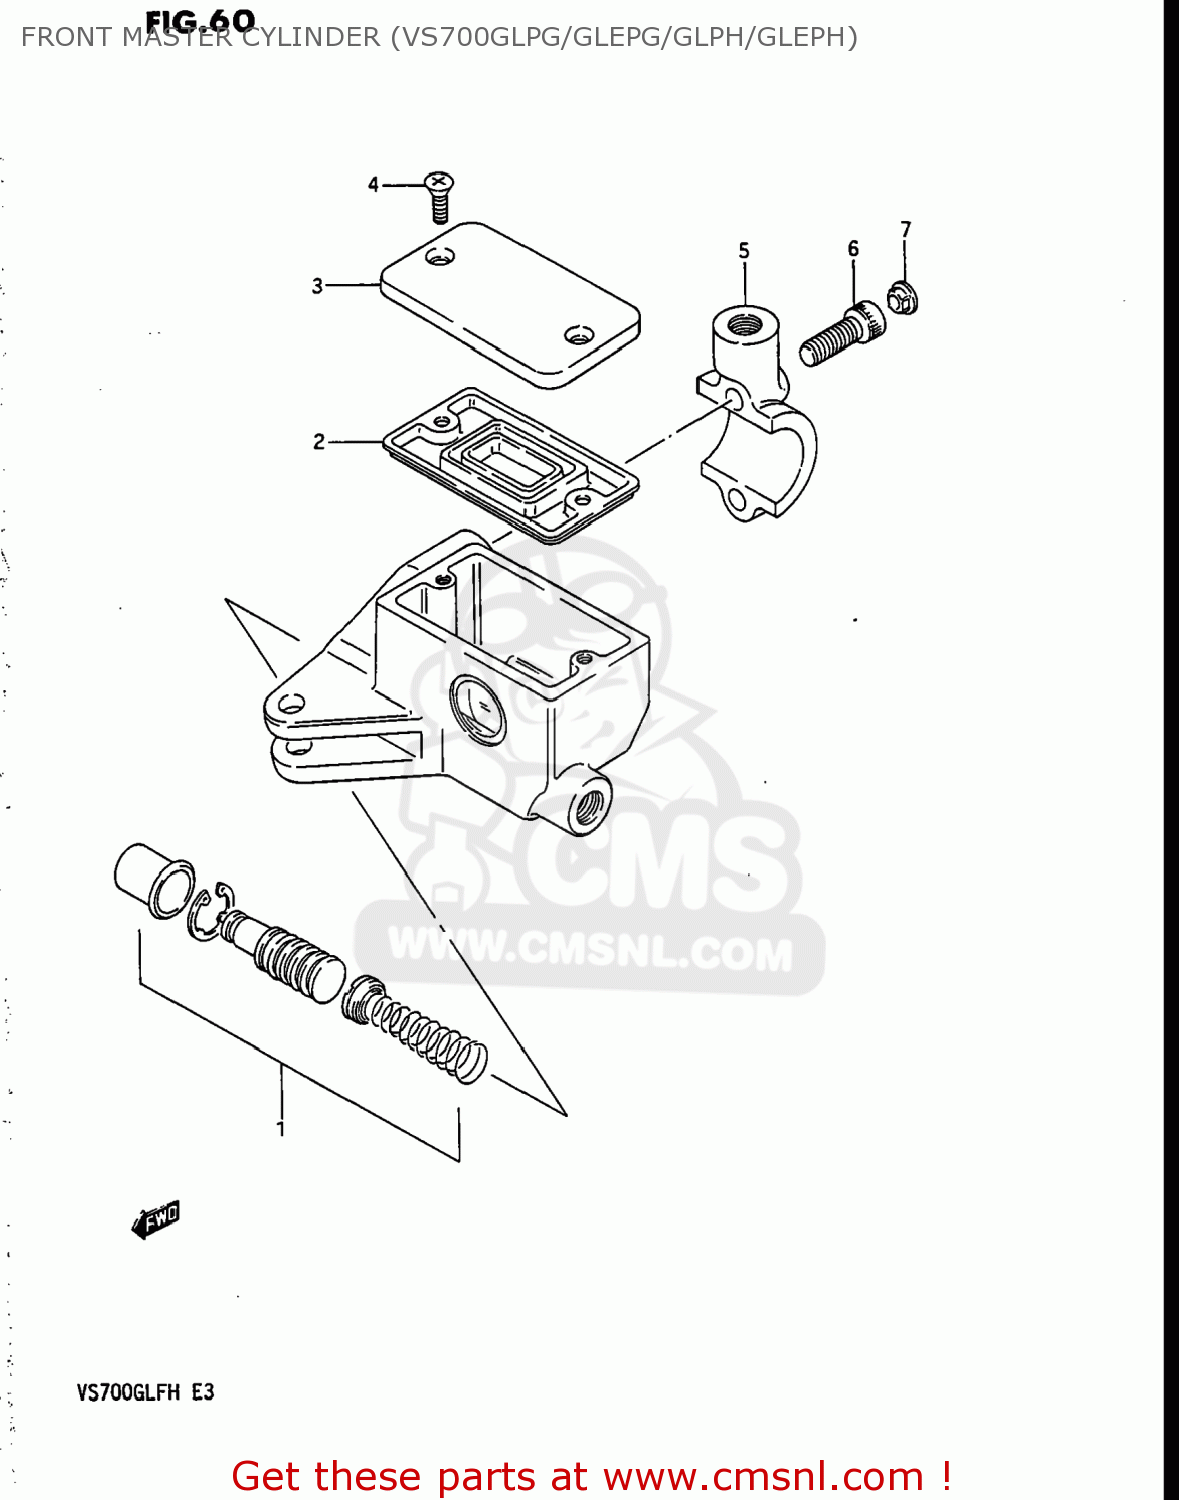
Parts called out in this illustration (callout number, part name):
1	PISTON & CUP SET
2	3
3	CAP
4	SCREW,RESERVOIR CAP
5	HOLDER
6	BOLT ,6X20
7	CAP(OD:10)
